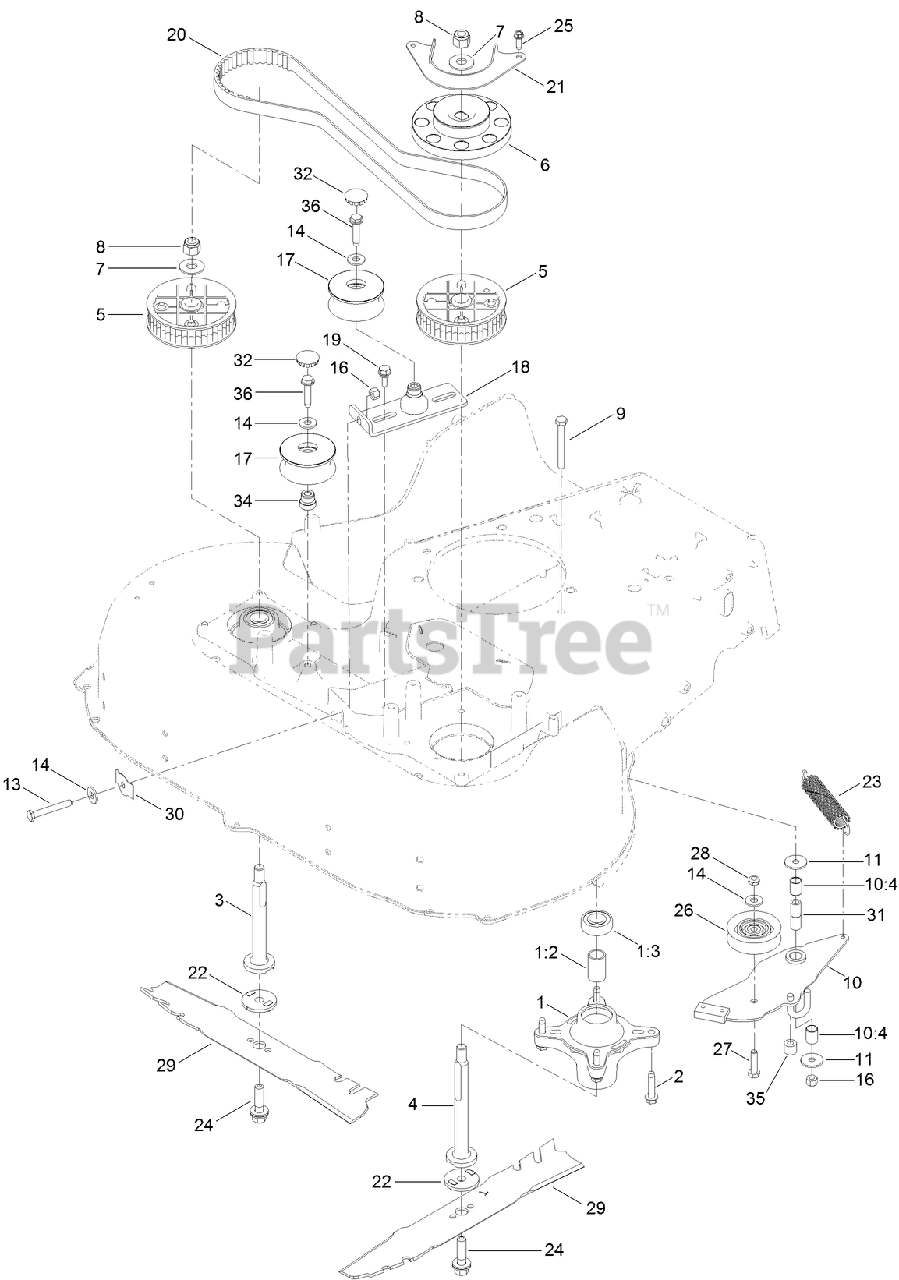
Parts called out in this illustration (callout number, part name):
1	SPINDLE ASM
1:2	SPACER
1:3	BEARING-BALL
2	SCREW-HWH
3	SHAFT-SPINDLE
4	SHAFT-SPINDLE
5	SPROCKET
6	PULLEY-BRAKE, SPINDLE
7	WASHER-SPRING
8	NUT-HEX
9	SCREW-HH
10	BRAKE ARM ASM
10:4	BUSHING-SLEEVE
11	WASHER-PIVOT
13	BOLT-TAP, HH
14	WASHER-FLAT
16	NUT-LOCK, NI
17	PULLEYS AND IDLER KIT
18	BRACKET-IDLER
19	SCREW-SHOULDER,HWH
20	BELT-SYNCHRONOUS
21	GUIDE-BELT, SPINDLE
22	ADAPTER-BLADE
23	SPRING-EXTENSION, BRAKE
24	BOLT-BLADE
25	SCREW-HWHTF
26	PULLEY-IDLER
27	SCREW-HH
28	NUT-LOCK, NI
29	BLADE-ROTARY
30	SPRING-FLAT
31	SPACER-BRAKE
32	PLUG-BUTTON
34	ADAPTER-BORE
35	HOSE-COOLANT
